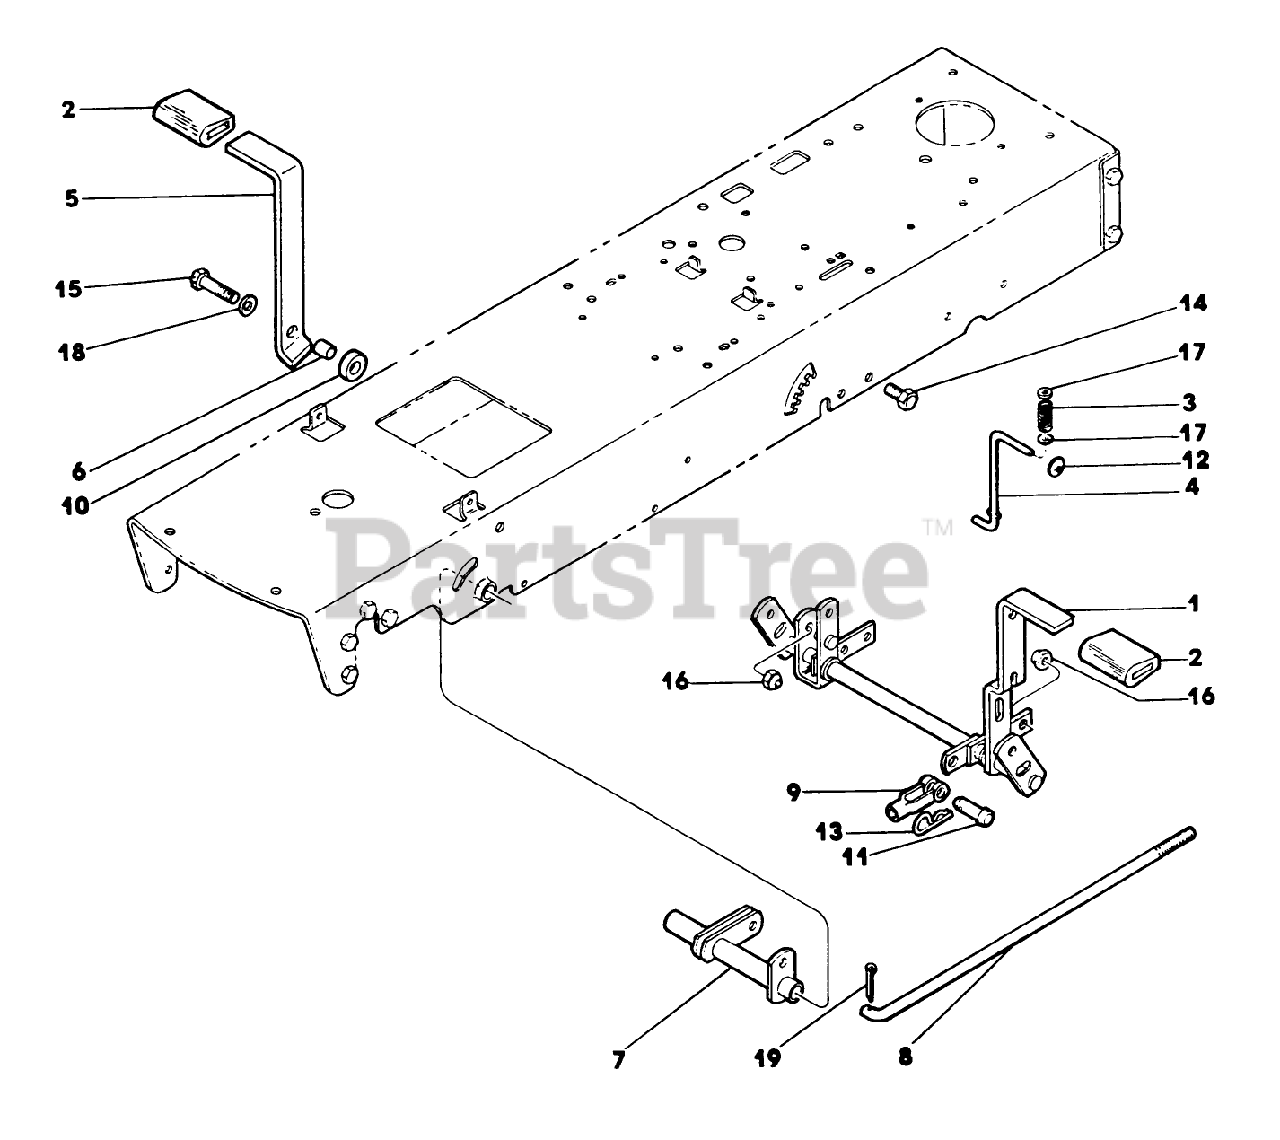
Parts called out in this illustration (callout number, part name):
2	GRIP
7	CROSS SHAFT WA*B
11	PIN CLEVIS
13	PIN - SPRING CLIP
16	NUT-LOCKING
18	WASHER
